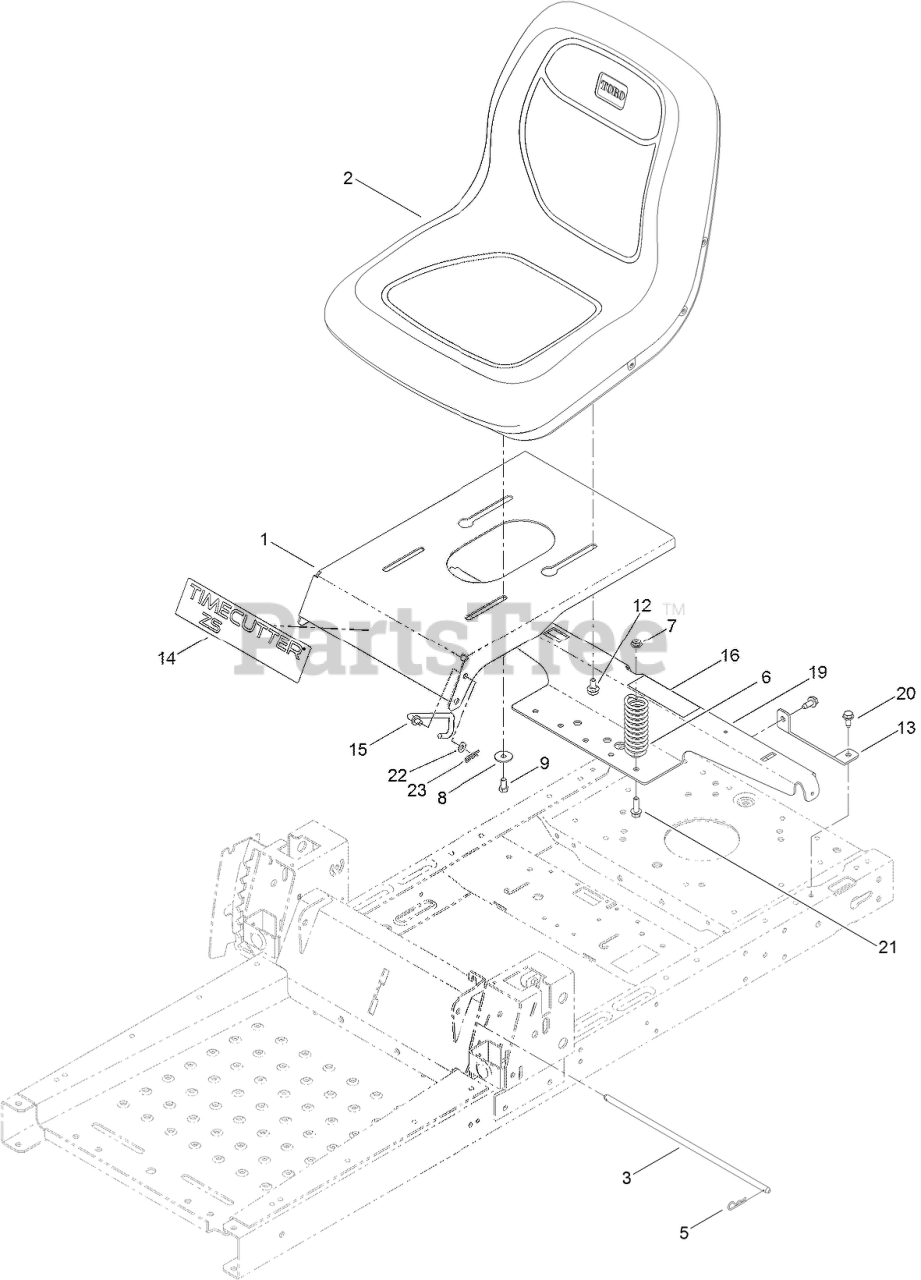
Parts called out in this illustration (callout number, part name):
1	PAN-SEAT
2	SEAT-18 INCH
3	ROD-PIVOT, NARROW
5	PIN-COTTER
6	SPRING-COMPRESSION
7	NUT-HF, NI
8	WASHER-PIVOT
9	SCREW-HH
12	BOLT-SHOULDER
13	SUPPORT-TANK, REAR
14	DECAL-TIMECUTTER
15	STOP-SEAT
16	DECAL-SERVICE, CE
19	SUPPORT-POD
20	SCREW-HWHTF
21	SCREW-HHF
22	WASHER-PLAIN
23	PIN-COTTER
